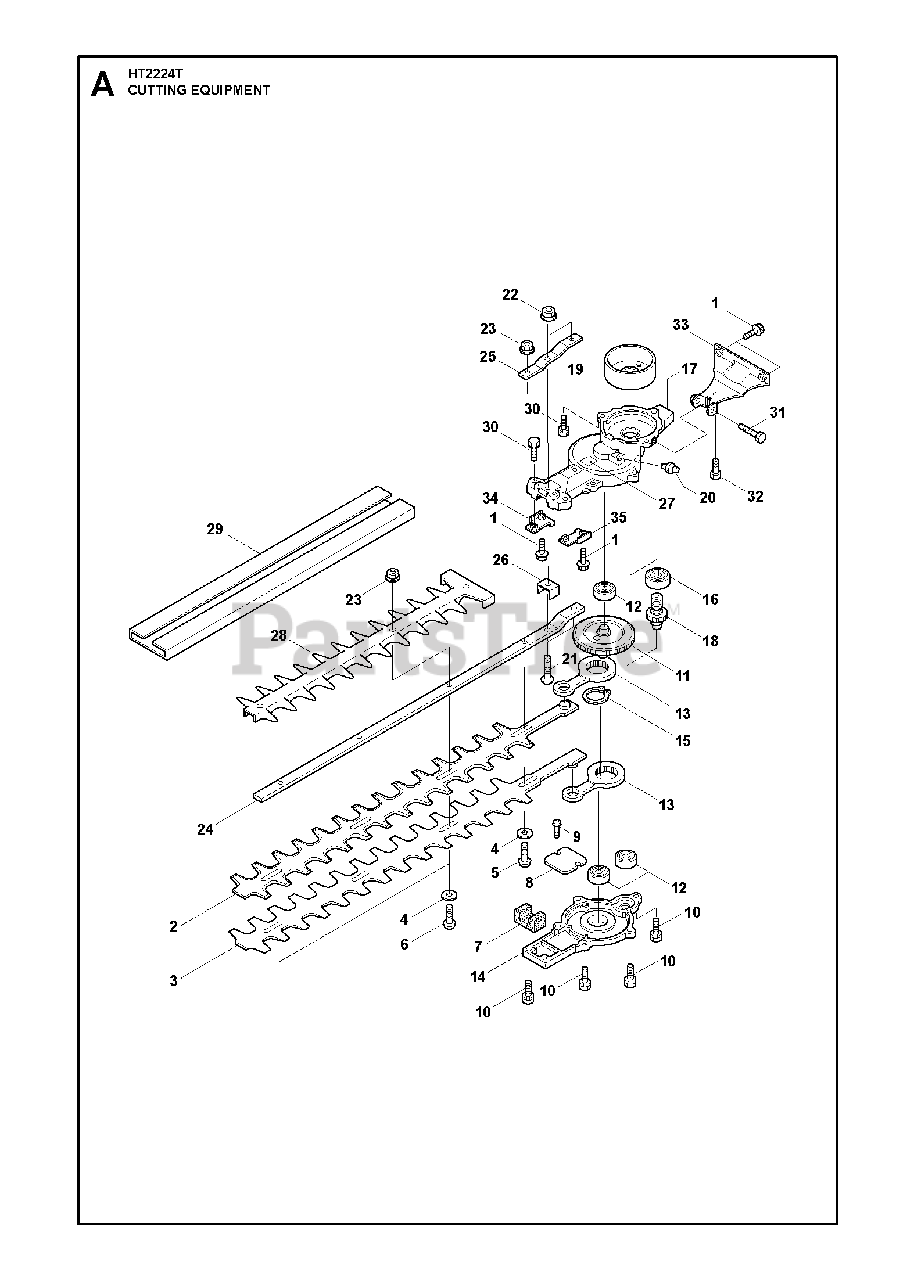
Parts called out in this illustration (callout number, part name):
15	RETAINING RING
18	PINION GEAR
19	CLUTCH DRUM
20	GREASE FITTING
29	BLADE COVER
